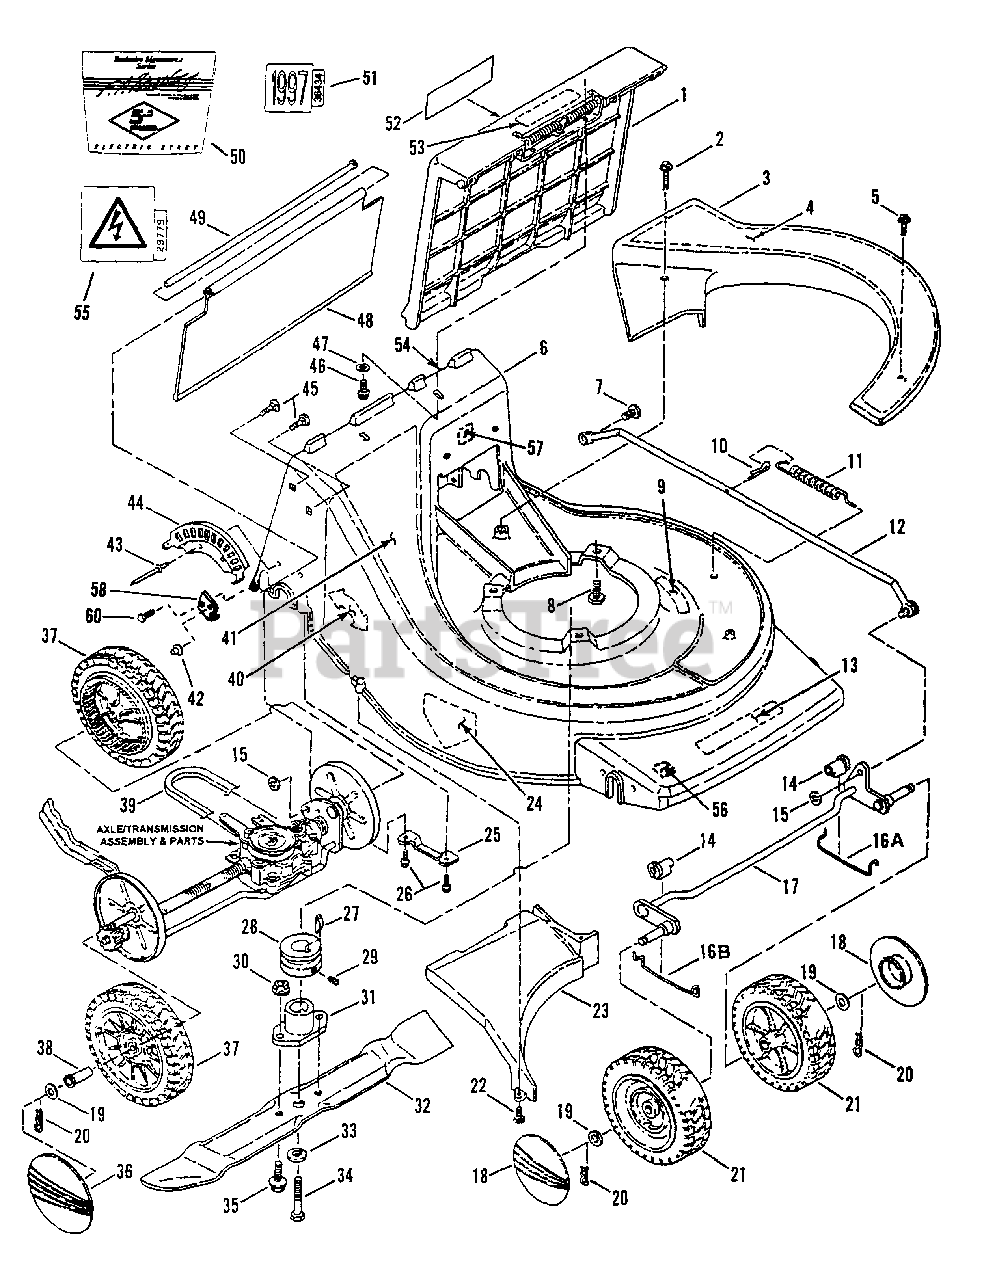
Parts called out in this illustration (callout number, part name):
1	ASSEMBLY, Discharge Door
2	SCREW, #10-24 x 1 1/2 Slotted, Hex Washer Head, Self-Tapping
3	COVER, Belt/Tie Bar
4	DECAL, Cover
5	SCREW, #10-24 x 1 Slotted, Hex Washer Head, Self-Tapping
6	DECK, 21" Cast Aluminum
7	PIN, Tie Bar, 3/8 x 5/8
8	SCREW, 3/8-18 x 1" Hex Head, Self-Tapping
9	DECAL - WARNING (Deck)
10	COTTER-PIN, 1/8 x 3/4
11	SPRING, Tie Bar
12	ASSEMBLY, Tie Bar
13	LOGO, SNAPPER Platinum Series
14	BUSHING, Front Axle
15	RETAINER, Wheel
16A	SPRING, Axle Retaining (Left Side)
16B	SPRING, Axle Retaining (Right Side)
17	ASSEMBLY, Front Axle
18	HUB-CAP, Front Wheels
19	WASHER, 1/2 Flat
20	HAIRPIN, .062 x .900
21	ASSEMBLY, Wheels (Front)
22	SCREW, #10-24 x 5/8" Slotted, Hex Washer Head, Self-Tapping
23	BAFFLE, Discharge
24	DECAL - DANGER
25	SUPPORT, Rear Axle
26	SCREW, 1/4-20 x 5/8 Hex Washer Head, Self-Tapping
27	KEY, HP-506 Hi-Pro
28	PULLEY, Traction Drive
29	SCREW, 5/16-18 x 5/16" Hex. Socket Set
30	NUT, 3/8-16 Hex Nyloc
31	HUB, 25 mm Blade Drive
32	BLADE, 21" Mulching/Bagging
33	WASHER, 3/8 Split Lock (Heavy)
34	SCREW, 3/8-24 x 1 3/4" Hex Head Cap, Grade 5
35	BOLT, 3/8-16 x 1 1/4" Hex Flange Lock
36	HUB-CAP, Rear Wheels
37	ASSEMBLY, Rear Drive Wheels
38	BUSHING, Rear Wheel
39	BELT, Traction Drive
40	DECAL, Height Adjustment
41	DECAL, Deck
42	PUSH-NUT, 1/4
43	RIVET, 3/16 x 1/2" Steel
44	PLATE, Height Adjustment
45	BOLT, 5/16-18 x 1" Carriage, Gr. 5
46	DECAL, Patent Numbers
47	WASHER, 1/4 Flat
48	SHIELD, Trailing
49	ROD, Trailing Shield Pivot
50	DECAL, Signature E.S.
51	DECAL, 1997 Year of Manufacture
52	DECAL, Convertible Mower
53	DECAL, WARNING
54	DECAL, Deck/Chute, International Warning
55	DECAL, Spark Plug
56	DECAL, European Community
57	DECAL, Noise Control
58	BRACKET, RH TS Pivot Rod
60	SCREW, 3/4-20 x 5/8 Hex Washer Head Self-Tapping
